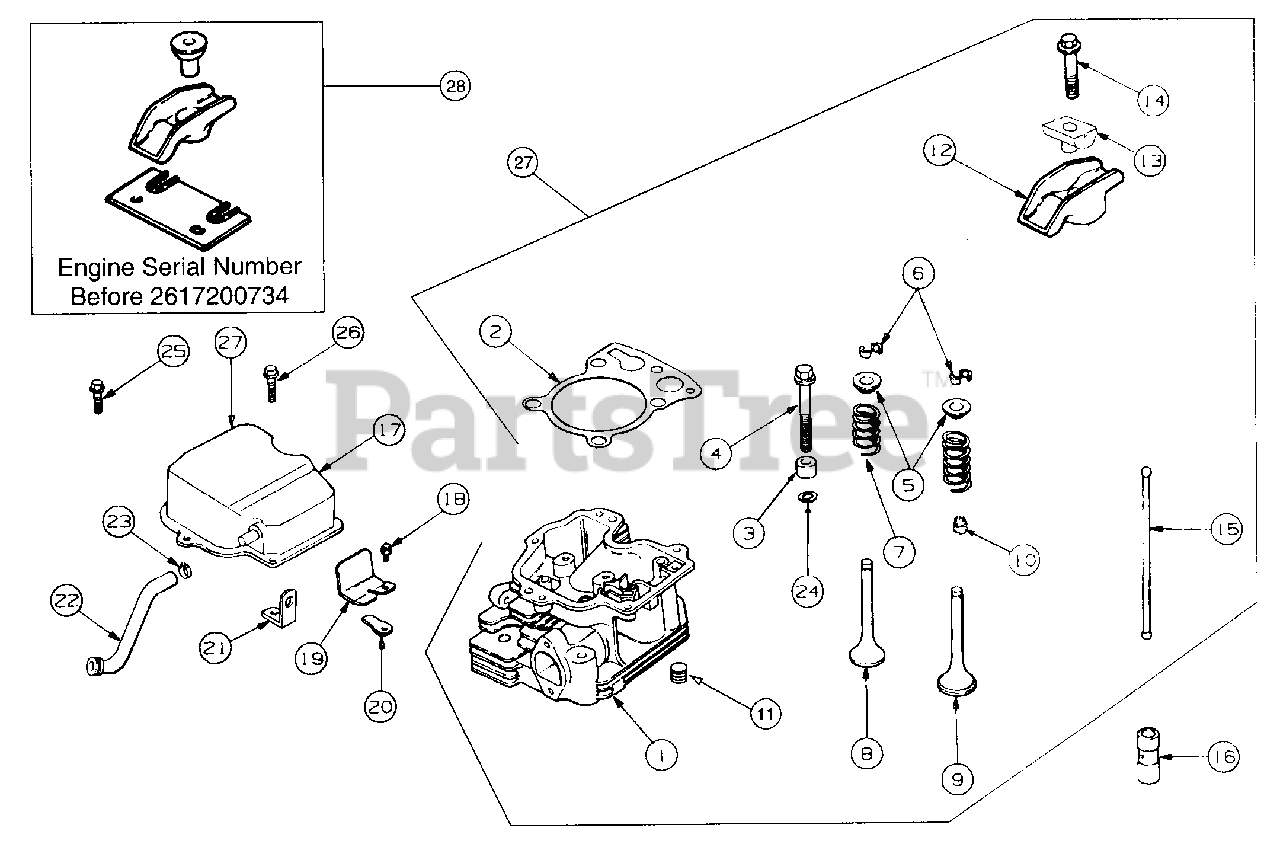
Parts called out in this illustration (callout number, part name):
1	Cylinder Head
2	Gasket, Cylinder Head
3	Spacer, Head Bolt Exhaust Port
4	Screw, Cylinder Head, M10 x 1.5 x 81
5	Cap, Valve Spring
6	Kit, Retainer
7	Spring, Valve
8	Valve, Exhaust, Std
9	Valve, Intake, Std
10	Seal, Valve Stem
11	Plug, Allen Hd. 1/8" Pipe
13	Pivot, Rocker Arm
14	Screw, Pivot Rocker, M6 x 1.0 x 34
15	Rod, Push
16	Lifter, Valve
17	Cover, Valve w/Nipple
18	Screw, Breather Reed Ret, M5 x .8 x 10
19	Retainer, Breather Reed
20	Reed, Breather
21	Strap, Lifting
22	Hose, Breather
23	Clamp, Hose
24	Washer, Flat
25	Screw, Hex Flange M6 x 1.0 x 20
26	Screw, Valve Cover, M6 x 1.0 x 25
27	Kit, Cylinder Head
28	Upgrade to Current Rocker Arm Assy.
